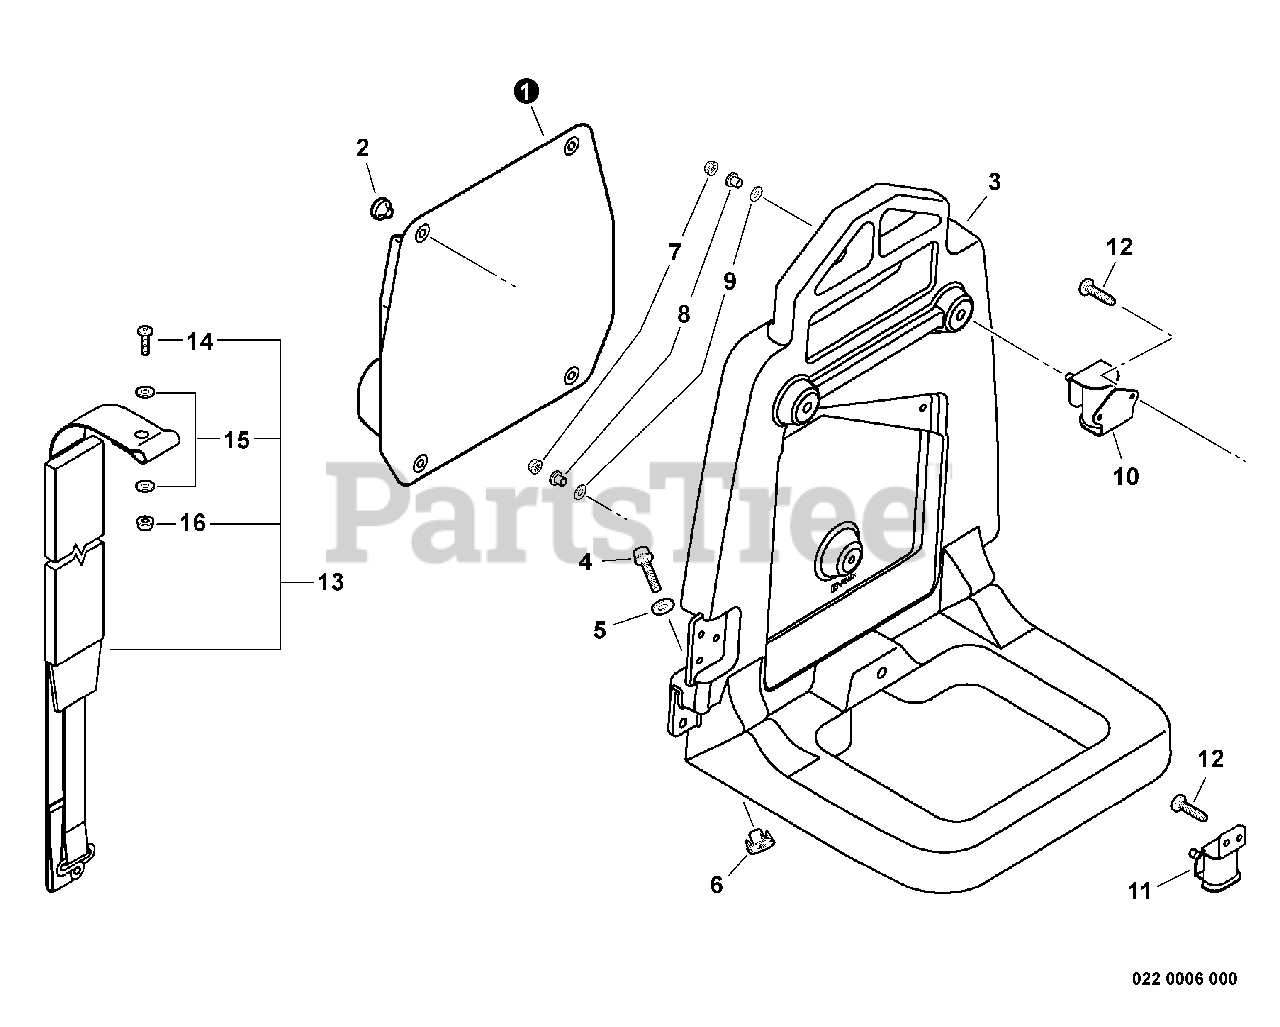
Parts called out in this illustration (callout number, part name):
1	CUSHION, BACKPACK
3	BACKPACK FRAME ASSY
4	BOLT 6×25
5	WASHER 6.6×20×1.6
7	NUT, LOCK M5
11	CUSHION
12	SCREW 5×16
13	BACKPACK STRAP ASSY
14	SCREW 5×14
15	WASHER 5.5×18×1
16	NUT, FLANGE M5
